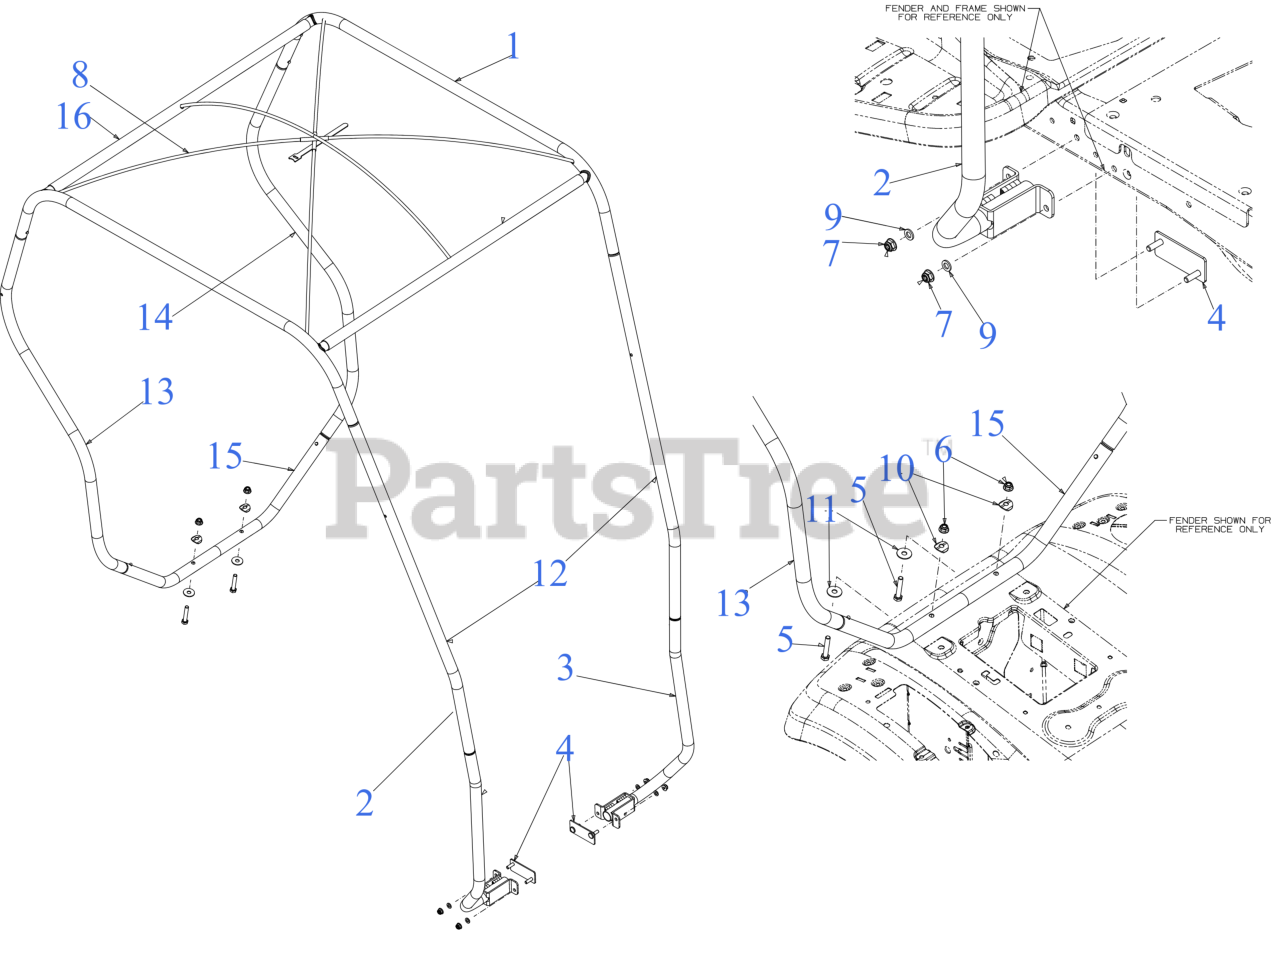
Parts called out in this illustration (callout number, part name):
1	SUPPORT TUBE ASSEMBLY
2	SUPPORT TUBE ASSEMBLY (FRONT RIGHT)
3	SUPPORT TUBE ASSEMBLY (FRONT LEFT)
4	MOUNTING PLATE ASSEMBLY
5	SCREW 5/16-18 x 1.75 GR5
6	FLANGE LOCK NUT 5/16-18
7	FLANGE LOCK NUT
8	FLEX CABLE RODS
9	FLAT WASHER .281 x .50 x .063
10	SADDLE WASHER
11	FLAT WASHER 344X1.00
12	FRONT SUPPORT TUBE
13	SUPPORT TUBE (REAR RIGHT)
14	SUPPORT TUBE (REAR LEFT)
15	REAR SUPPORT TUBE
16	CROSS SUPPORT TUBE
